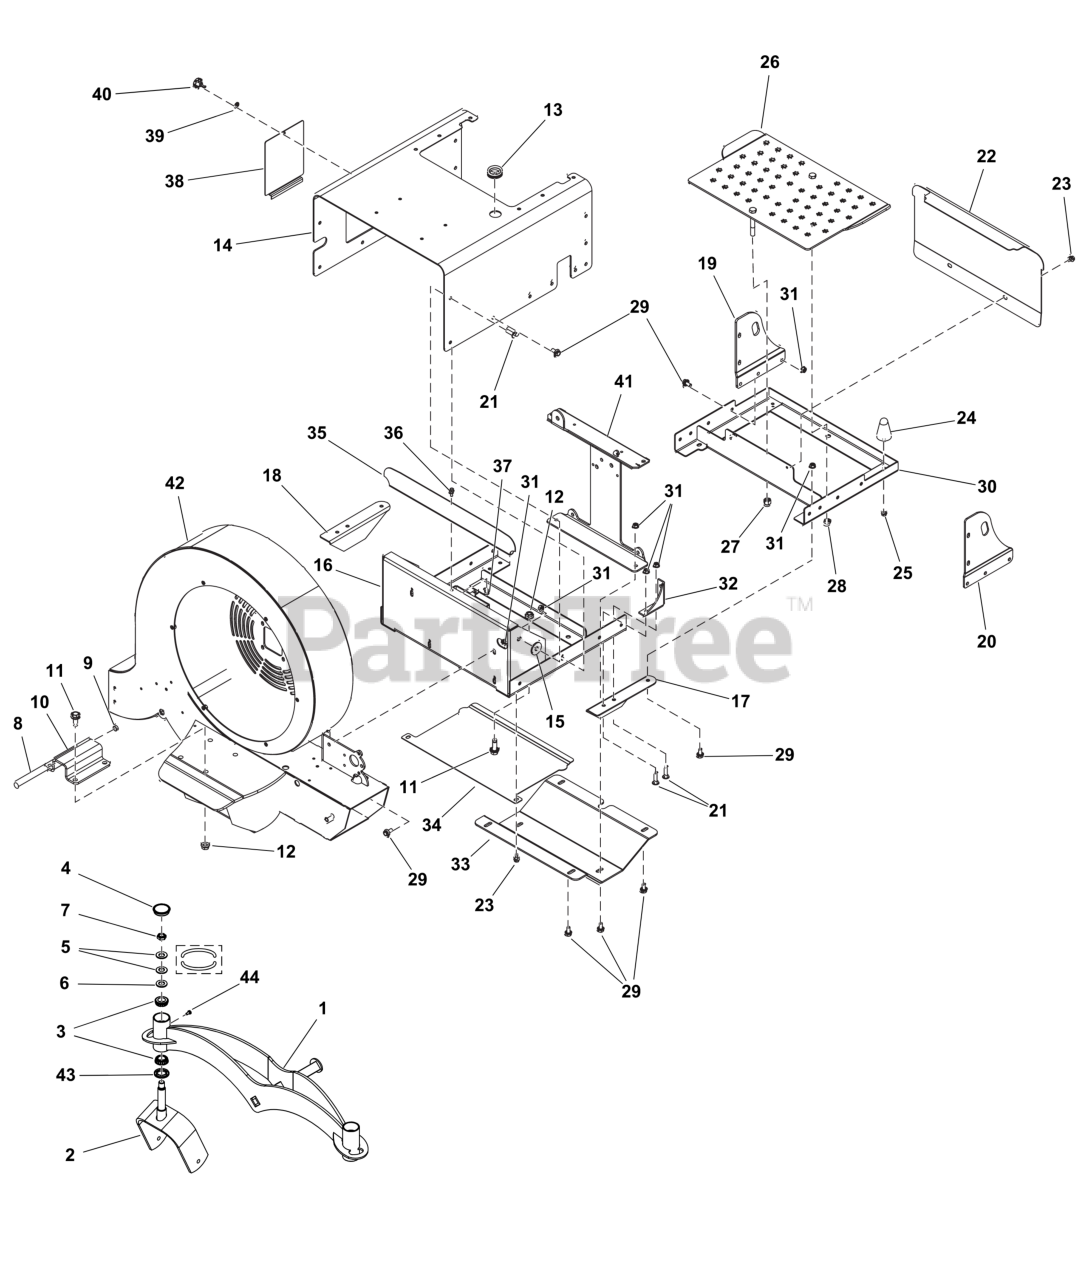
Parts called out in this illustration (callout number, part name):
1	WELD, FRONT END PIVOT, X3 - BLK
2	YOKE, CASTER
3	BEARING, TAPERED ROLL
5	WASHER, BELLEVILLE
6	WASHER, 3/4" SAE
7	NUT - 3/4-16 HEX JAM
9	RUBBER BAND
13	GROMMET, RUBBER
14	BOX, MOTOR
16	BOX, FRAME
19	PLATE, TIE DOWN RH - BLK
20	PLATE TIE DOWN LH - BLK
22	PLATE, TOE KICK, FB2000 - BLK
25	NUT, 5/16-18 HEX SERR
30	FRAME, Rear
32	SUPPORT, Transaxle
40	CAPSCREW
41	TRANS, I-BEAM
42	WELD, BLOWER HOUSING, X3000, CE - ORG
43	SEAL, GREASE
44	BOLT - 1/4-28 X 1/2
